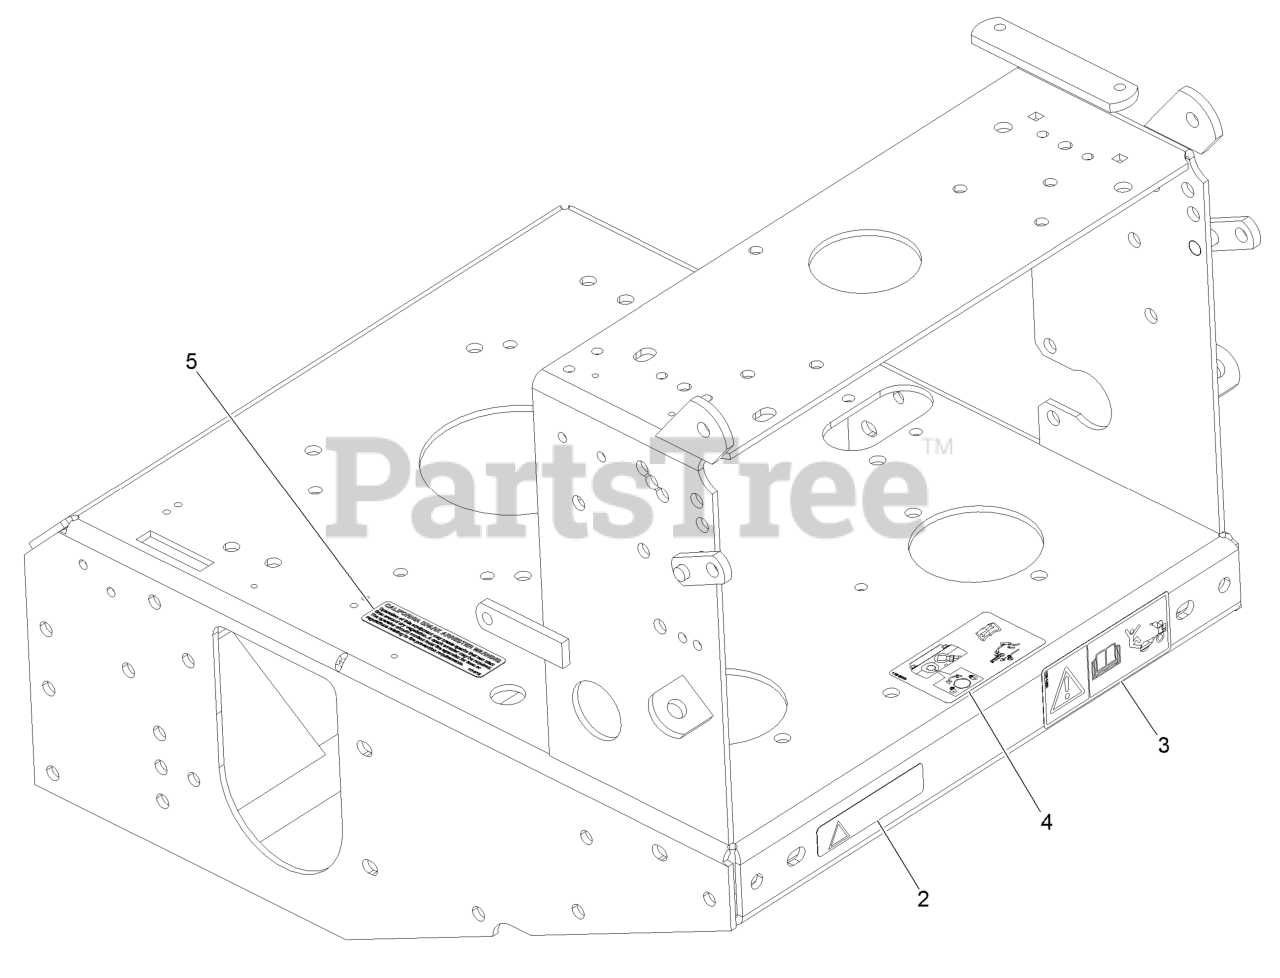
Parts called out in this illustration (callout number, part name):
2	DECAL-WARNING
3	DECAL-WARNING, SULKY
4	DECAL-DRIVE RELEASE
5	DECAL-ARRESTER, SPARK
